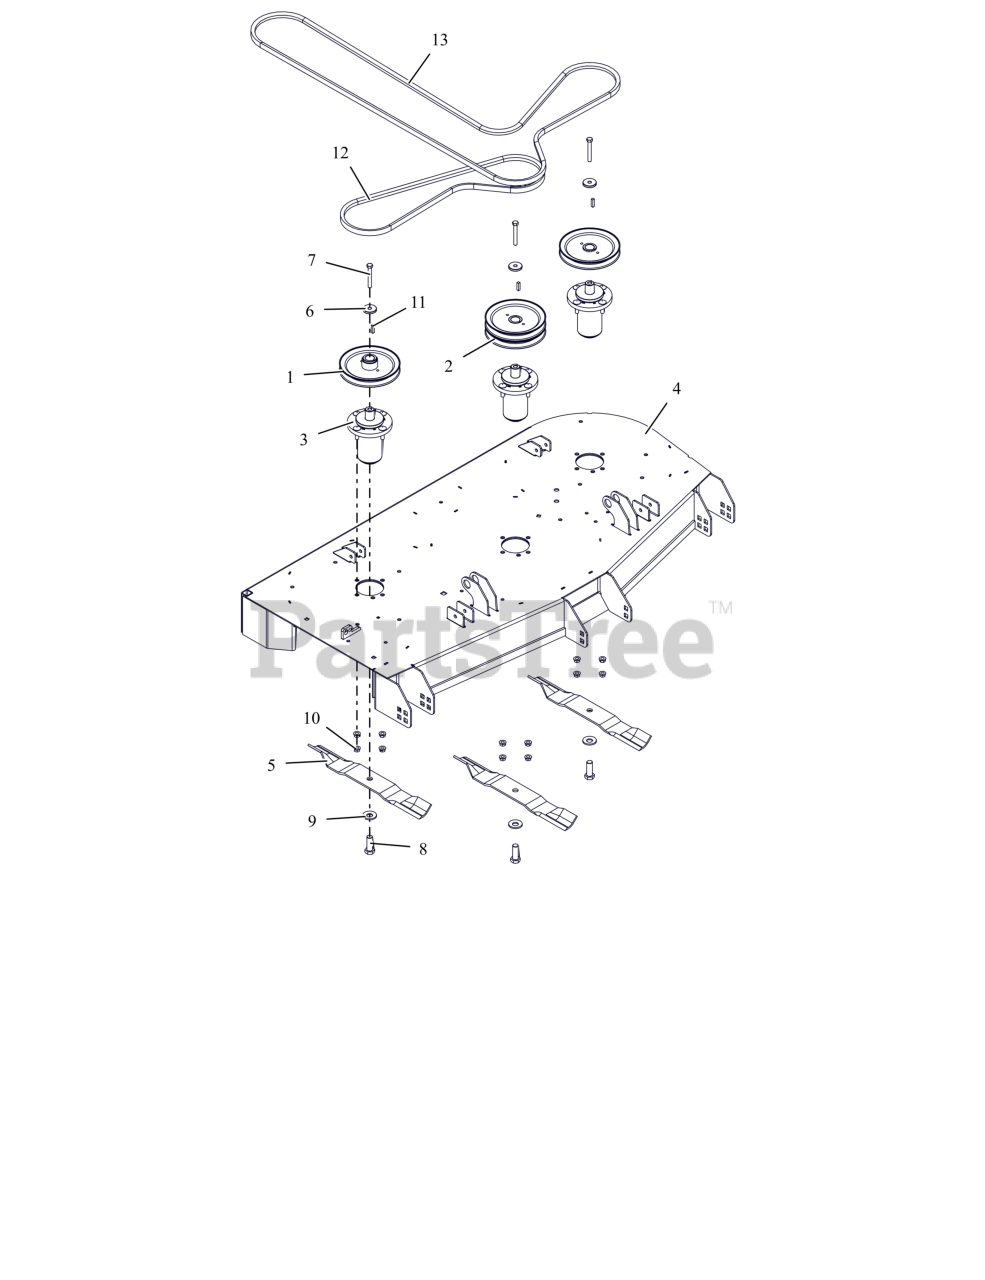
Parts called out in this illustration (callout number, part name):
1	PULLEY, V-1.000 ID X 6.750 OD
2	PULLEY, DOUBLE 1.000 ID X 6.750 OD-BLACK
3	ASM, MAINT FREE ALUM SPINDLE
4	KIT,DECK-52" W/DECALS -ARIENS
5	BLADE, 18"
6	RETAINER, SHEAVE
7	BLT, HEX .38-16X2.75 G8 ZCC
8	BLT, HEX .62-18X1.75 G8 ZCC
9	WSHR-BLVL .669X1.535X.138
10	NUT-LK-CTR-FLG .375-16 GF ZCC
11	KEY, SQ .25X.25X1.00 RC 40-50
12	V-BELT, B-COGGED
13	V-BELT, HB SECTION
